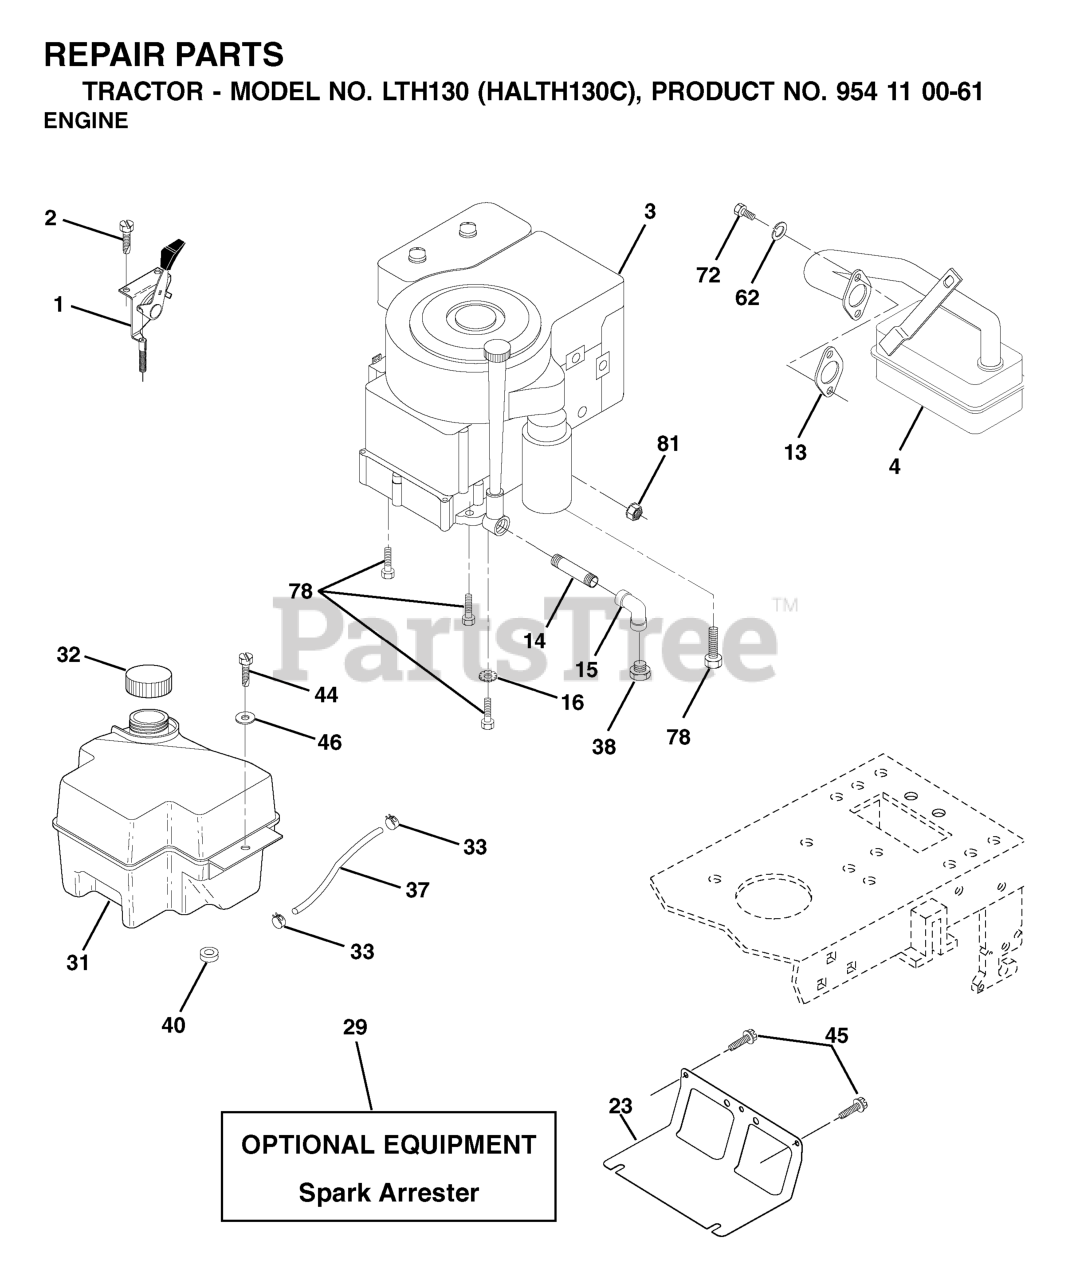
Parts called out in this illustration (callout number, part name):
1	CHOKE CONTROL
2	SCREW LT
4	MUFFLER.SINGLE.B&S.10-12HP
13	REPL BY 532 27 22-93
14	Nipple Pipe 3/8 Npt X 3-1/2
15	ELBOW
16	LOCKWASHER
23	SHIELD.BROWNING.DBR.GUARD
29	KIT.SPARK ARRESTOR 794945 B&S
31	FUEL TANK
32	FUEL CAP
33	HOSE CLAMP
37	LINE.FUEL.20
40	BUSHING.SNAP.NYL.BLK.
44	SCREW HEXWSHR 1/4-20X3/4
45	SCREW, 3/8-16X3/4
62	WASHER.LOCK.HVY.HLCL.SPR.5/16
72	SCREW
78	SCREW.3/8-16
81	NUT
